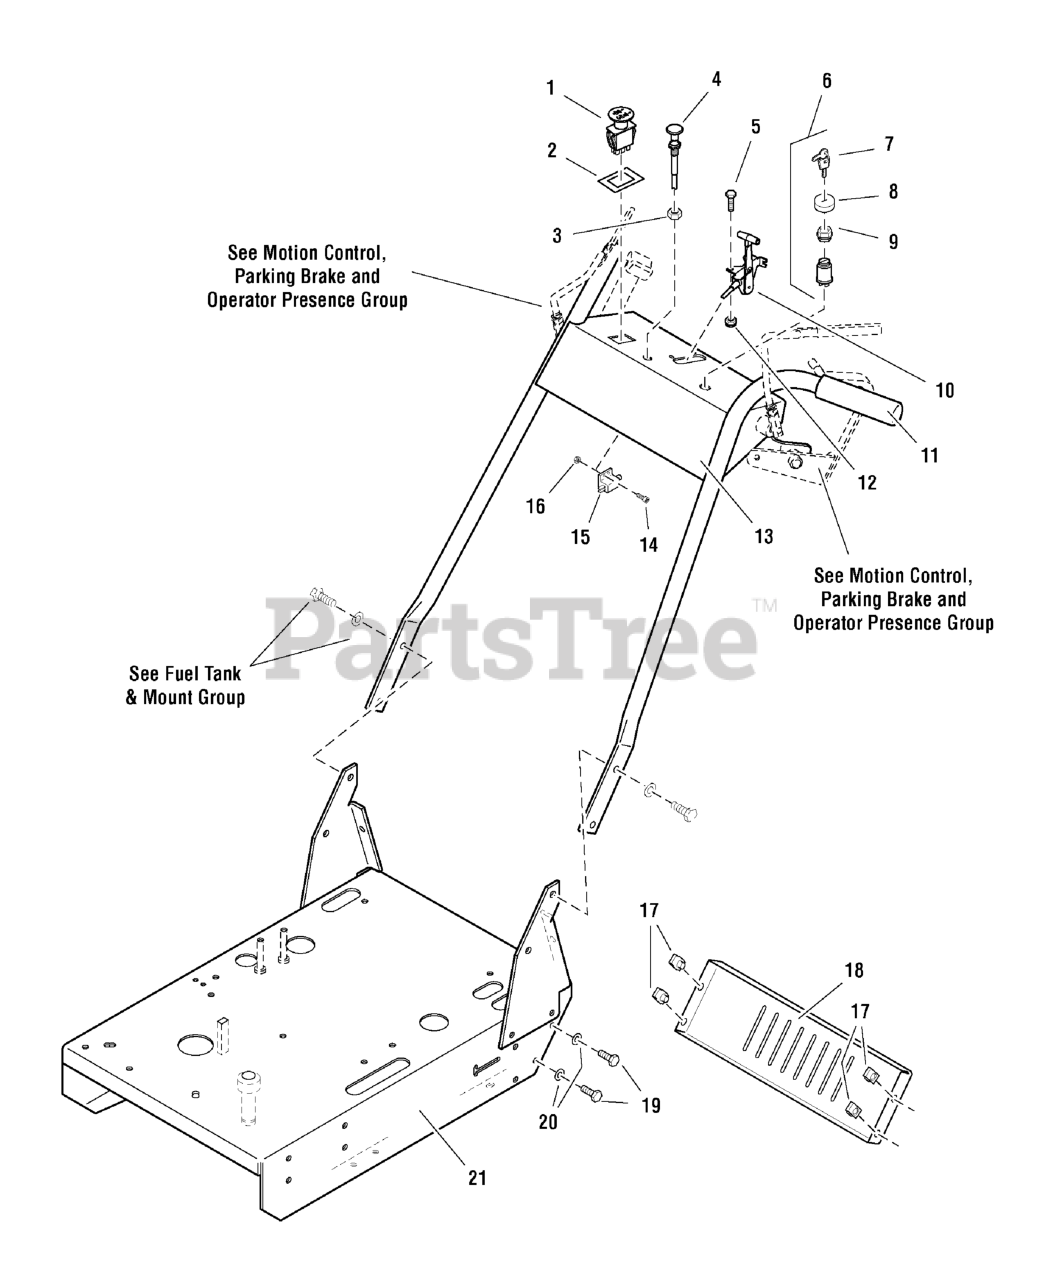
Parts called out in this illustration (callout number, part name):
1	SWITCH, BLADE ENGAGEMENT
2	SWITCH RETAINER RING
3	NUT, 3/8-24 HEX
4	CABLE, Choke Control, 47"
5	BOLT, 1/4-20 x 3/4
6	SWITCH, Ignition, Complete
7	KEY, IGNITION MOLDED SET
8	COVER, PLASTIC, SNAP ON
9	PLASTIC NUT
10	CABLE, Throttle Control, 46"
11	GRIP, FOAM, .940" X 4.62" X .187"
12	NUT, 1/4-20 HEX NYLON LOCK
13	ASSM, WELD, HANDLE BAR, HC WITH DECALS
14	SCREW, #10-24 x 1/2
15	SWITCH, PLUNGER, N.C.
16	NUT, #10-24 HEX
17	BODY CLIP, 5/16-18-7GA MATERIAL
18	REAR SHIELD
19	BOLT, 5/16-18 X 3/4 GD5
20	WASHER, 5/16" SAE
21	ENGINE DECK ASSEMBLY
